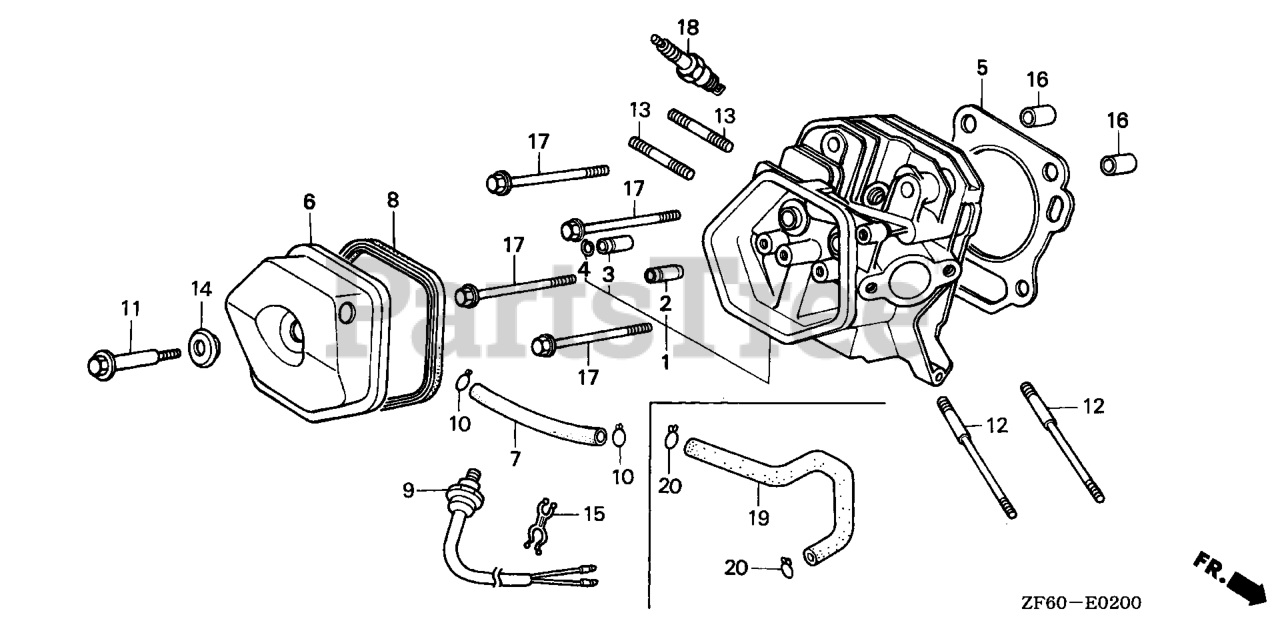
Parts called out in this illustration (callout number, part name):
1	CYLINDER HEAD
2	GUIDE, VALVE (OVER SIZE)
4	CLIP, VALVE GUIDE
5	GASKET, CYLINDER HEAD Use up to Engine SN 2949254.
5	GASKET, CYLINDER HEAD
6	COVER, HEAD
7	BULK HOSE, VACUUM (11X1000) (Honda Code 4537312). (11X105)
8	GASKET, CYLINDER HEAD COVER
11	BOLT, HEAD COVER
12	BOLT, STUD (8X131.5)
13	BOLT, STUD
14	WASHER, HEAD COVER
16	PIN A, DOWEL (12X20)
17	BOLT, FLANGE (10X80)
18	SPARK PLUG (BPR5ES) (NGK)
18	SPARK PLUG (W16EPR-U) (DENSO)
18	SPARK PLUG (BPR6ES) (NGK)
18	SPARK PLUG (W20EPR-U) (DENSO)
